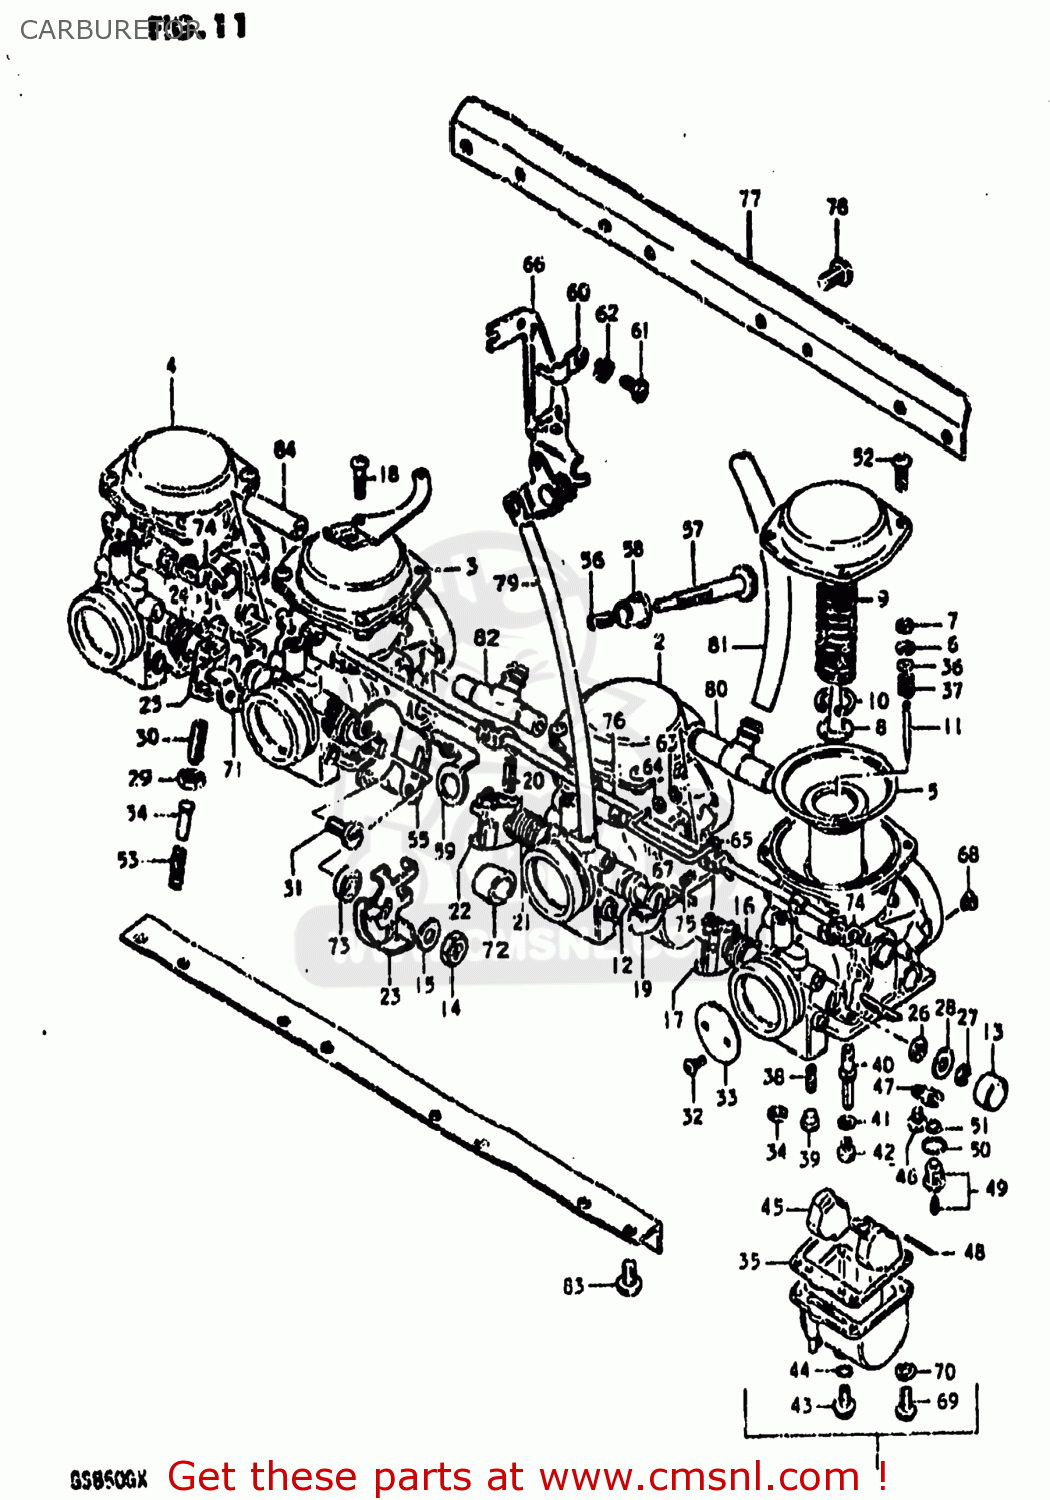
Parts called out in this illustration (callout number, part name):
1	CARBURETOR ASSEMBLY
2	CARBURETOR ASSEMBLY
3	CARBURETOR ASSEMBLY
4	CARBURETOR ASSEMBLY
5	DIAPHRAGM
6	CLIP,NEEDLE
7	RING
8	HOLDER,GUIDE
9	SPRING
10	E RING
11	NEEDLE JET
12	GASKET,THROTTLE SHAFT (NAS)
13	CAP
14	NUT
15	WASHER
16	SPRING,THROTTLE SHAFT
17	SHAFT,THROTTLE
18	SCREW
19	SHAFT ASSEMBLY
20	PIN,THROTTLE SHAFT
21	SPRING,THROTTLE SHAFT
22	LEVER,THROTTLE SHAFT
23	LEVER ASSEMBLY,THROTTLE
24	SPRING,THROTTLE SHAFT
25	SHAFT,THROTTLE
26	SEAL
27	E RING
28	GASKET,THROTTLE SHAFT (NAS)
29	NUT
30	SCREW
31	SCREW
32	SCREW
33	VALVE,THROTTLE
34	GASKET (NAS)
35	GASKET,FLOAT CHAMBER (NAS)
36	WASHER
37	SPRING
38	JET,PILOT
39	PLUG,NEEDLE JET
40	JET,NEEDLE
41	WASHER,NEEDLE NOZZLE
42	JET,MAIN(115)
43	PLUG,DRAIN
44	GASKET (NAS)
45	FLOAT
46	SCREW
47	PLATE
48	PIN,FLOAT
49	VALVE ASSEMBLY,NEEDLE
50	O RING
51	FILTER
52	SCREW
53	SPRING,THROTTLE SCREW
54	PIN,THROTTLE LEVER
55	BRACKET,THROTTLE ADJUST
56	SPRING
57	SCREW
58	BUSH
59	BRACKET,THROTTLE ADJUST
60	BRACKET,STARTER
61	BOLT
62	LOCK WASHER
63	CAP,LEVER
64	SEAT,SPRING
65	LEVER ASSY
66	BRACKET
67	ROD,STARTER LEVER
68	JET,AIR(190)
69	SCREW
70	LOCK WASHER
71	SHAFT ASSEMBLY
72	RING
73	RING
74	LEVER
75	SCREW
76	SHAFT,STARTER
77	BRACKET
78	SCREW
79	HOSE
80	NIPPLE
81	HOSE
82	NIPPLE
83	SCREW
84	NIPPLE,CARBURETOR
